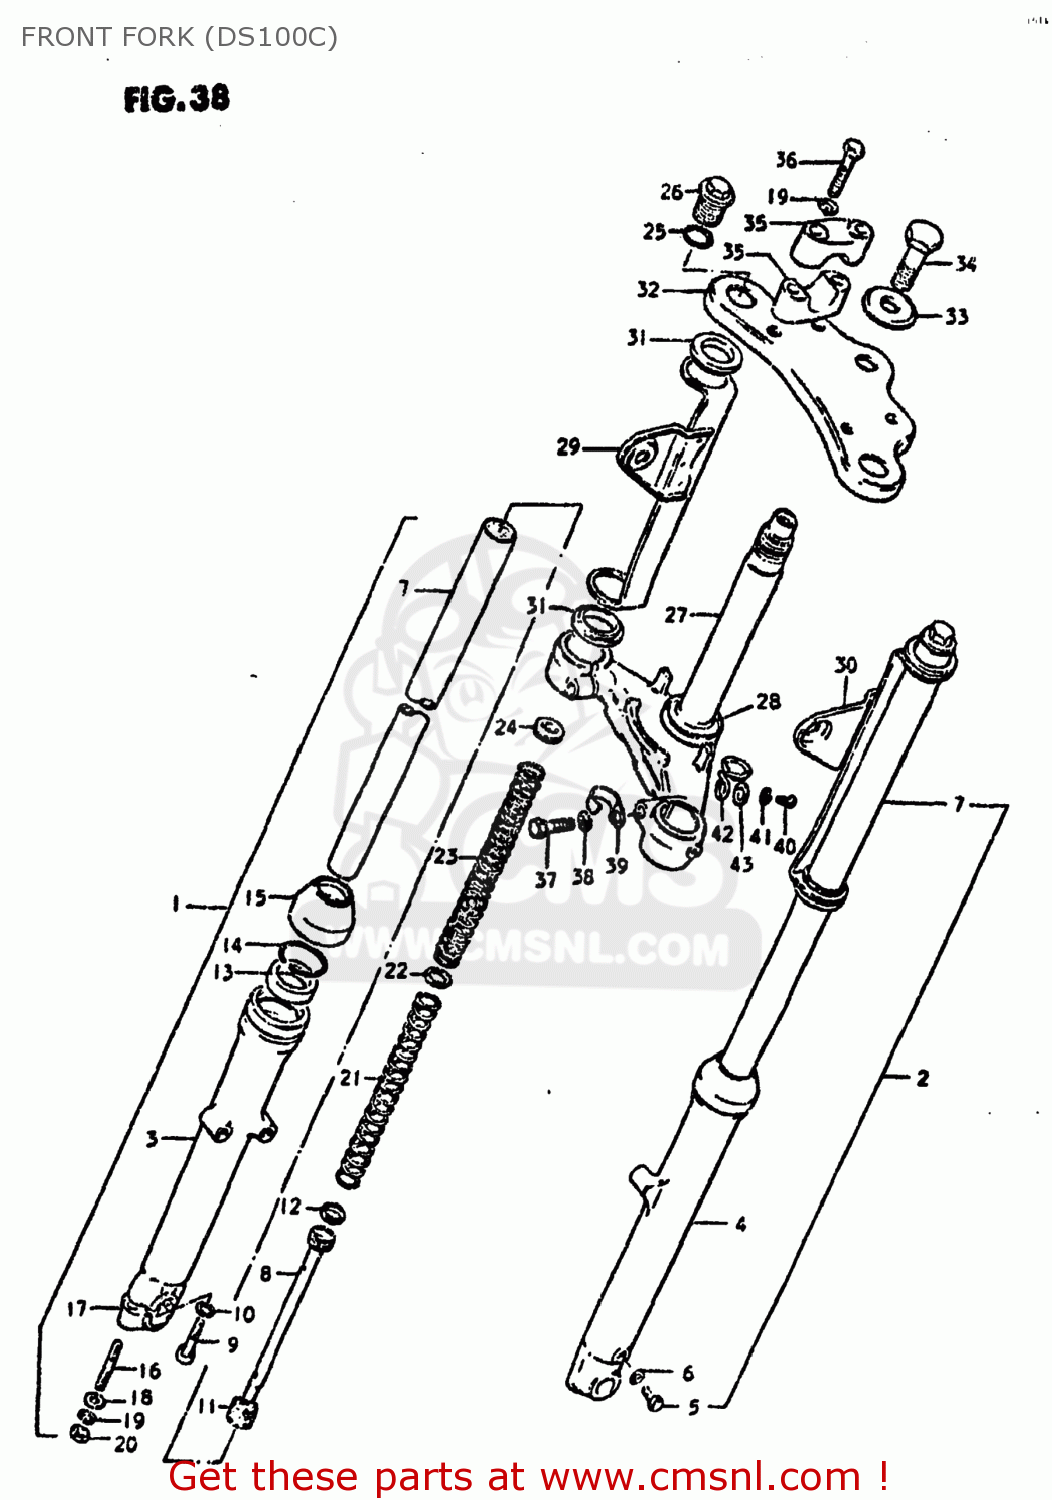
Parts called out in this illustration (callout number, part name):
1	DAMPER ASSEMBLY,RIGHT
2	DAMPER ASSEMBLY,LEFT
3	TUBE,FORK,OUTER,RIGHT
4	TUBE,FORK,LEFT,OUTER
5	BOLT(6X8)
6	GASKET,DRAIN,PLUG (NAS)
7	TUBE,FORK,INNER
8	PIPE,FORK SEAT
9	BOLT(8X27)
10	GASKET (NAS)
11	SPRING,REBOUND
12	RING,PISTON
13	OIL SEAL,FRONT FORK
14	RING,OIL SEAL STOPPER
15	DUST SEAL,FRONT FORK
16	STUD 8X25
17	HOLDER,AXLE(BLACK)
18	WASHER
19	LOCK WASHER
20	NUT
21	SPRING,FRONT FORK
22	JOINT,SPRING
23	SPRING,FRONT FORK
24	NUT,FORK SPRING,UPPER
25	O-RING,FORK INNER TUBE
26	CAP
27	STEM,STEERING
28	RACE,STEERING OUTER LWR
29	BRACKET,HEADLAMP,RIGHT
30	BRACKET,HEADLAMP,LEFT
31	CUSHION
32	HEAD,STEERING STEM
33	WASHER
34	BOLT
35	HOLDER,HANDLE UPR
36	BOLT 8X55
37	BOLT
38	WASHER,LOCK 12
39	CLIP
40	SCREW 6X12
41	LOCK WASHER
42	CLIP
43	WASHER
